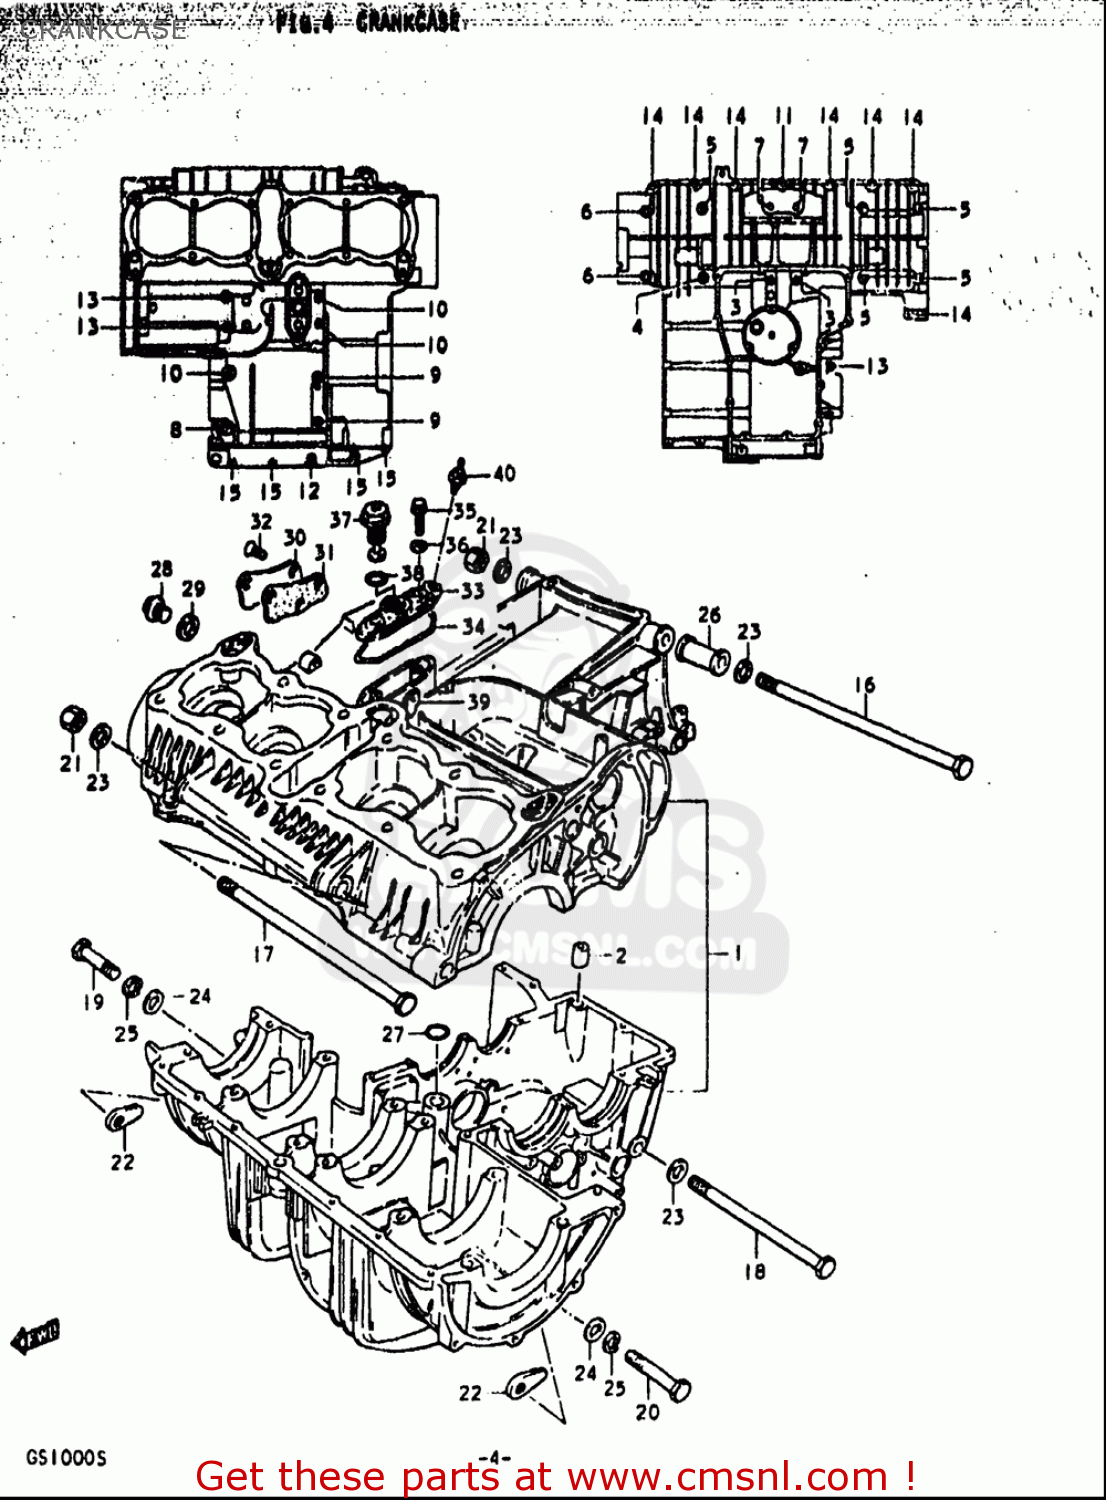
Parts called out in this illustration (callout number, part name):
2	PIN
3	BOLT(8X125)
4	BOLT(8X100)
5	BOLT
6	BOLT
7	BOLT
8	BOLT
9	BOLT
10	BOLT
11	BOLT
12	BOLT
13	BOLT
14	BOLT
15	BOLT
16	BOLT 10X265
17	BOLT 10X250
18	BOLT(10X165)
19	BOLT
20	BOLT
21	NUT
22	NUT
23	WASHER
24	WASHER(10.5X20X3.2)
25	WASHER,LOCK
26	SPACER
